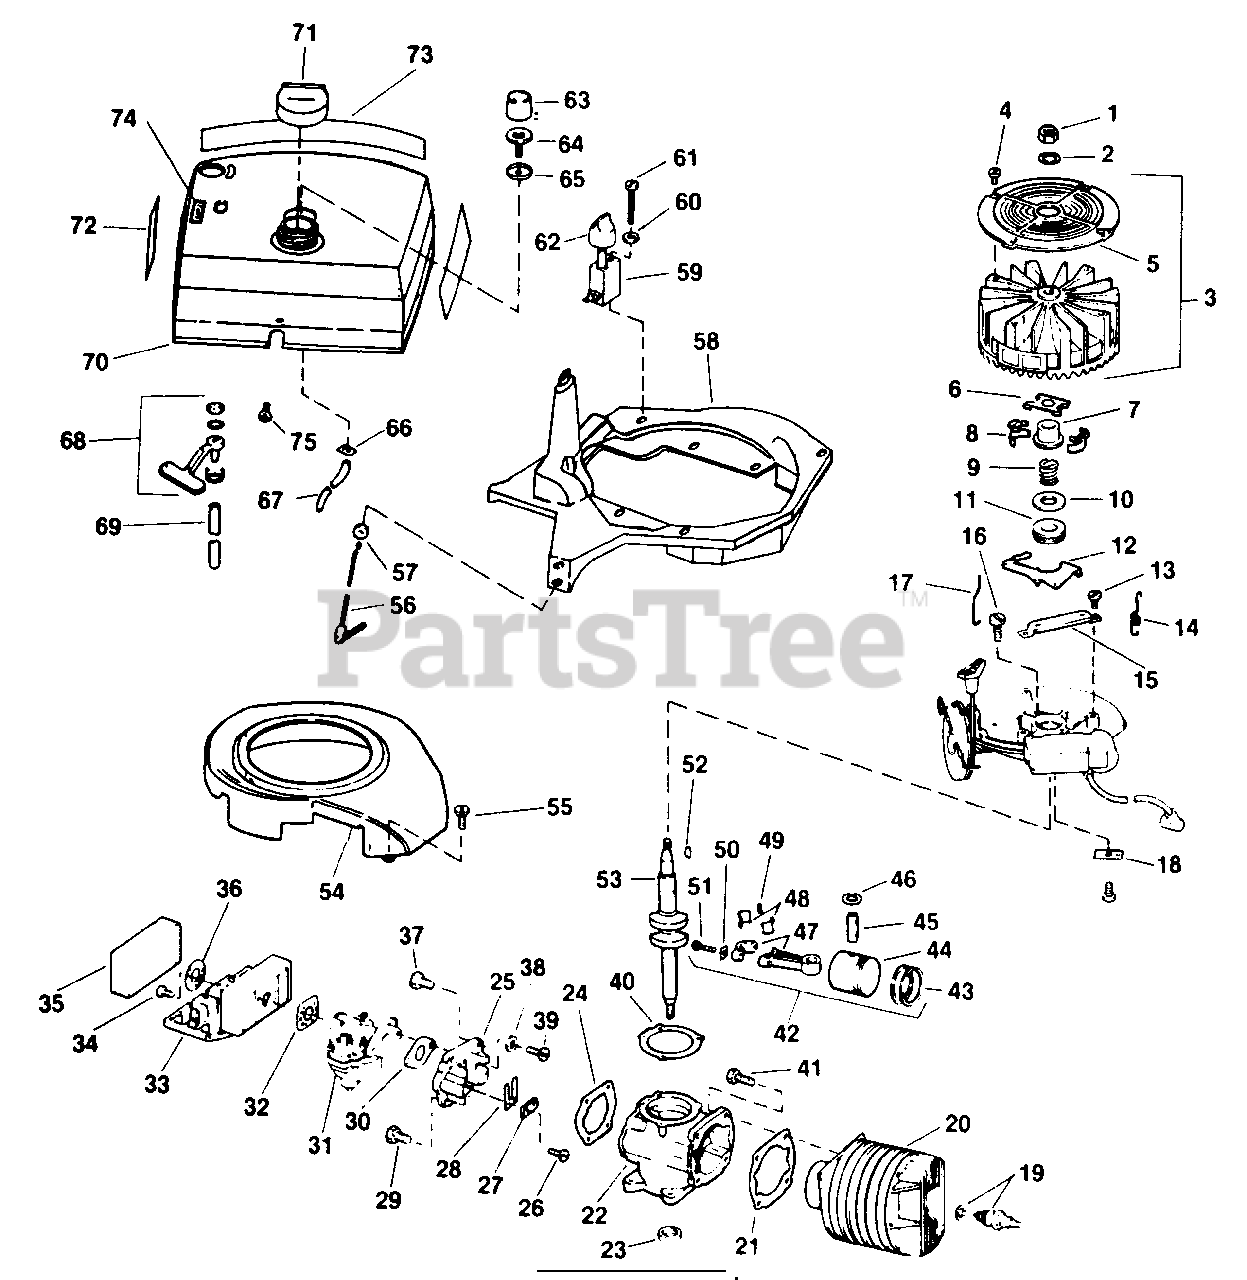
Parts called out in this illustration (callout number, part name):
1	Nut
2	Lockwasher
3	Flywheel & Screen Assy.
4	Screw
5	Screen
6	Yoke
7	Collar
8	Weight
9	Spring
10	Thrust Washer
11	Collar
12	Lever
13	Screw
14	Spring
15	Bracket
16	Screw-Arm. Plt. to Crankcase
17	Rod
18	Tab
19	Spark Plug Champion CJ-14 .035" Gap
20	Cylinder
21	Gasket
22	Crankcase & Seal
23	Seal
24	Gasket
25	Reed Plate Assembly
26	Screw-Reed to Plate
27	Plate
28	Reed
29	Screw
30	Gasket
31	Carburetor
32	Gasket
33	Case-Air Filter
34	Screw
35	Element
36	Washer
37	Screw
38	Washer
39	Screw
40	Gasket
41	Screw
42	Piston & Connecting Rod Assembly
43	Ring Set
44	Piston
45	Wrist Pin
46	Retaining Ring
47	Connecting Rod & Bearings
48	Liners
49	Needle Bearing Set
50	Lockplate
51	Screw
52	Key
53	Crankshaft
54	Air Baffle
55	Screw
56	Knob & Rod
57	Grommet
58	Shroud-Base
59	Shorting Switch
60	Washer
61	Screw
62	Knob
63	Bulb-Primer
64	Base-Primer
65	Cap-Primer
66	Fastener-Primer Base
67	Gas Line
68	Fuel Shut-off Assy.
69	Fuel Hose
70	Shroud-Tank Engine
71	Fuel Cap
72	Decal
73	Decal-Lawn-Boy
74	Decal-Caution
75	Screw
